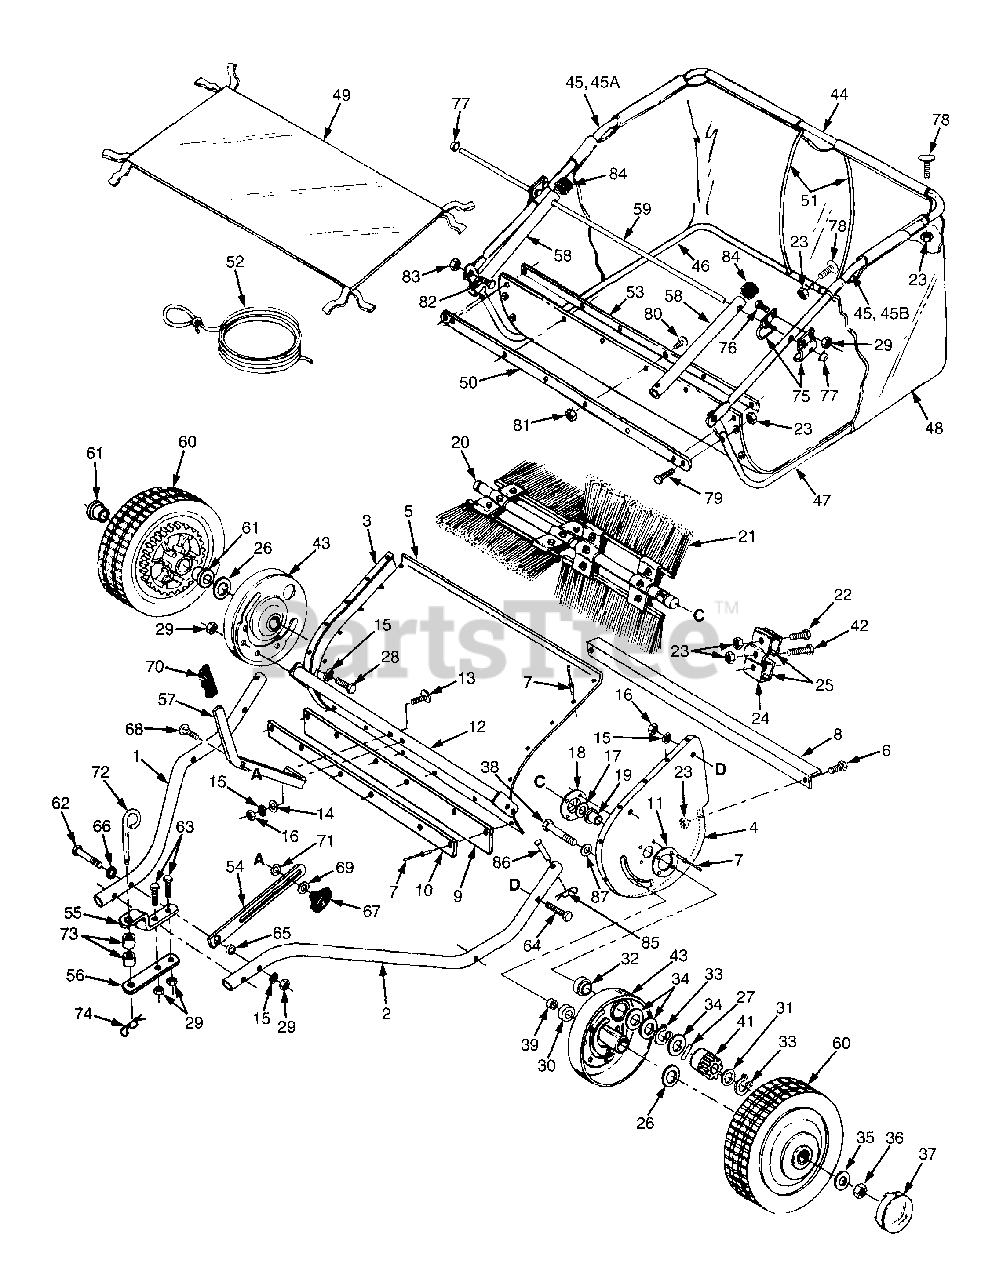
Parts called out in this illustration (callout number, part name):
1	Hitch Tube, R.H.
2	Hitch Tube, L.H.
3	End Plate, R.H.
4	End Plate, L.H.
6	Bolt, Hex 1/4-20 x 1/2" Lg.
8	Brace, Rear Support
9	Skirt, 42"
10	Retainer, Skirt
11	Washer, Special
12	Height Adjustment Tube Ass'y.
13	Bolt, Cvd. Hd. 5/16-18 x 1-5/8" Lg.
14	Washer,Bowed 1" x .32" x .06"
15	Lock Washer, 5/16"
16	Nut,Hex 5/16-18 Thread
17	Washer, 5/8"
18	Retainer, Dust Cover
19	Bushing, Brush Shaft
20	Brush Shaft
21	Brush, 42"
22	Bolt, Hex 1/4-20 x 3/4" Lg.
23	Nut, Hex Lock 1/4-20 Thread
24	Retainer, Brush (Double)
25	Retainer, Brush (Single)
26	Washer, Flat 1-1/8" x .78" x .025"
27	Dowel Pin (Drive)
28	Bolt, Hex 5/16-18 x 1/2" Lg.
29	Nut, Hex Lock 5/16-18 Thread
30	Spacer, .39 I.D". x 1-1/4" O.D. x .5"
31	Washer, Flat .849" x .598" x .025"
32	Spacer, .78 I.D". x 1-1/4" O.D. x .5"
33	Ring, Retaining .594"
34	Washer, Shim 1.125" x .594" x .025"
35	Washer, Flat 1-1/2" x .375" x .062"
36	Nut, Hex Lock 3/8-24 Thread
38	Bolt, Hex 3/8-24 x 3-1/4" Lg.
39	Bushing, Spacer
41	Gear, Pinion L.H.
42	Bolt, Hex 1/4-20 x 1" Lg.
43	Ass'y, Dust Cover
44	Tube, Upper Hopper Frame (Mid)
45	Tube, Upper Hopper Frame (Side)
45A	Tube, Upper Hopper Frame R.H.
45B	Tube, Upper Hopper Frame L.H.
46	Tube, Lower Hopper Frame R.H.
47	Tube, Lower Hopper Frame L.H.
48	Hopper Bag
49	Wind Screen
50	Strap, Bag Frame
51	Rod, Hopper Support
52	Hopper Rope
53	Retainer, Bag
54	Strap, Height Adjustment
55	Bracket, Hitch
56	Bracket, Hitch (Straight)
57	Handle, Height Adjustment
58	Tube, Bag Arm
59	Rod, Hopper Bag Pivot
60	Wheel & Tire Ass'y. (with bearings)
61	Wheel Bearing
62	Bolt, Hex 5/16-18 x 3" Lg.
63	Bolt, Hex 5/16-18 x 2-1/4" Lg.
64	Bolt, Hex 5/16-18 x 1-3/4" Lg.
65	Bushing, Spacer
66	Washer, Flat (5/16) 11/32" x 11/16"
67	Knob, Wing 5/16-18 Thread
68	Bolt, Carriage 5/16-18 x 3/4" Lg.
69	Washer, Flat 5/16" Std. Wrt.
70	Grip, Height Adjust
71	Washer, Tooth Lock 5/16"
72	Pin, Hitch
73	Tube, Hitch Spacer
74	Hairpin Cotter, 1/8" #4
75	Clamp, Hopper Mount
76	Bolt, Hex 5/16-18 x 3/4" Lg.
77	Palnut, 3/8"
78	Bolt, Cvd. Hd. 1/4-20 x 1" Lg.
79	Bolt, Hex 1/4-20 x 1-1/4" Lg.
80	Bolt, Sl. Tr. Hd. #10-32 x 5/8" Lg.
81	Nut, Hex Lock #10-32 SEMS
82	Bolt, Hex 3/8-16 x 3/4" Lg.
83	Nut, Hex Lock 3/8-16 Thread
84	Cap, Vinyl
85	Hairpin Cotter, 3/32" #3
86	Pin, Clevis 1/4" x 1-1/2" Lg.
87	Washer, 3/8" Std. Wrt
